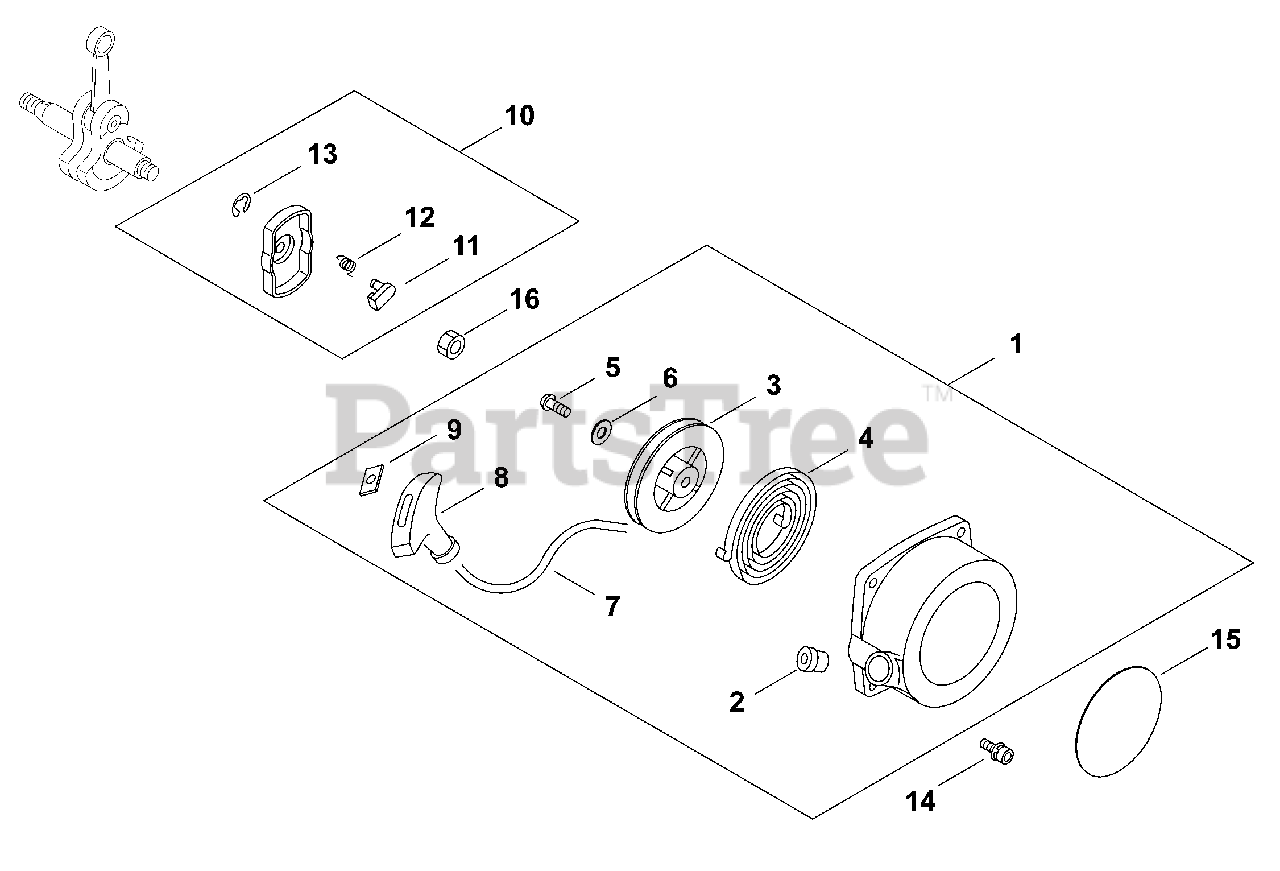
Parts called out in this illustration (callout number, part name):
1	STARTER ASSY
2	GUIDE, ROPE
3	REEL, ROPE
4	SPRING, RECOIL
7	ROPE, STARTER 4.0×880
8	GRIP, STARTER
9	RETAINER, ROPE
10	PULLEY ASSY, STARTER
11	PAWL, STARTER
12	SPRING, RETURN
13	E-RING 4
14	BOLT 4×20
15	LABEL, STARTER - SHINDAIWA
16	NUT 8×1.25
